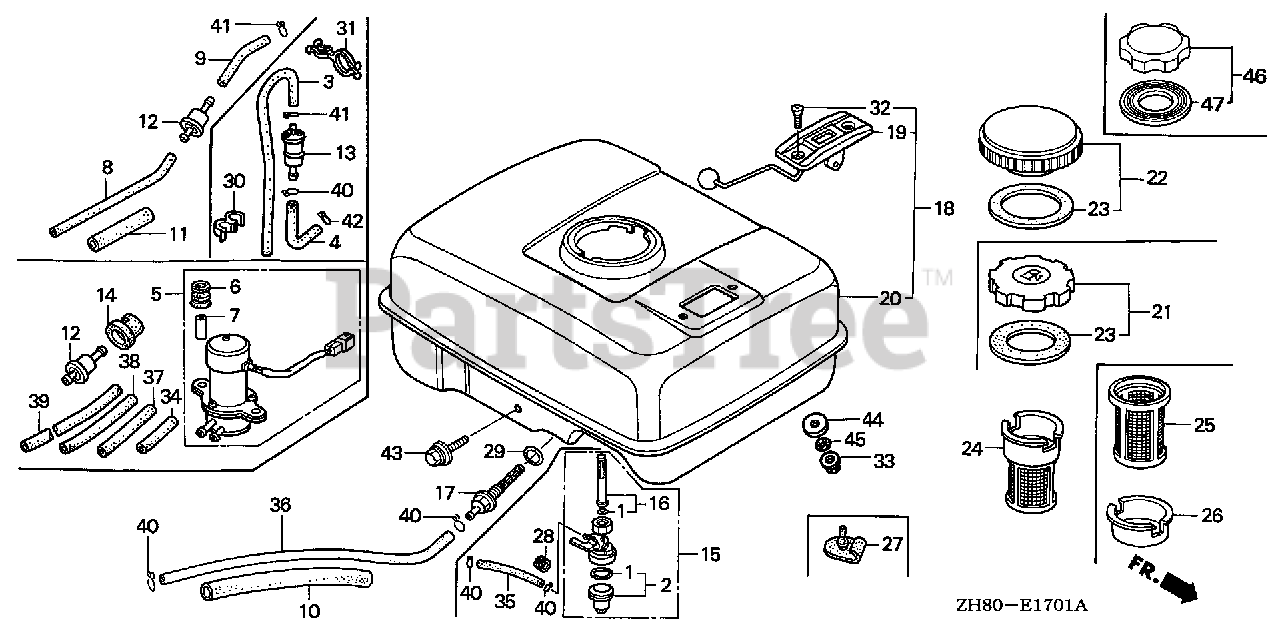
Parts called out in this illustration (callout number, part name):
10	RUBBER, SUPPORTER (107MM)
17	JOINT, FUEL TANK
20	TANK, FUEL *NH1* (BLACK)
20	TANK, FUEL *R280* (POWER RED)
21	CAP, FUEL FILLER (BLACK)
22	CAP, FUEL FILLER (CHROME PLATED)
22	CAP, FUEL FILLER
23	GASKET, FUEL FILLER CAP (39X58X3)
29	O-RING (14MM) (ARAI)
29	O-RING (14MM) (NOK)
33	NUT, FLANGE (6MM)
36	BULK HOSE, FUEL (4.5X3000) (4.5X140)
40	CLIP, TUBE (B8)
43	BOLT, FLANGE (6X25)
46	CAP, FUEL FILLER (CHROME PLATED)
46	CAP, FUEL FILLER (CHROME PLATED)(TOUYOUSYA)
47	GASKET, FUEL FILLER CAP (39X62X3) (TOUYOUSYA)
